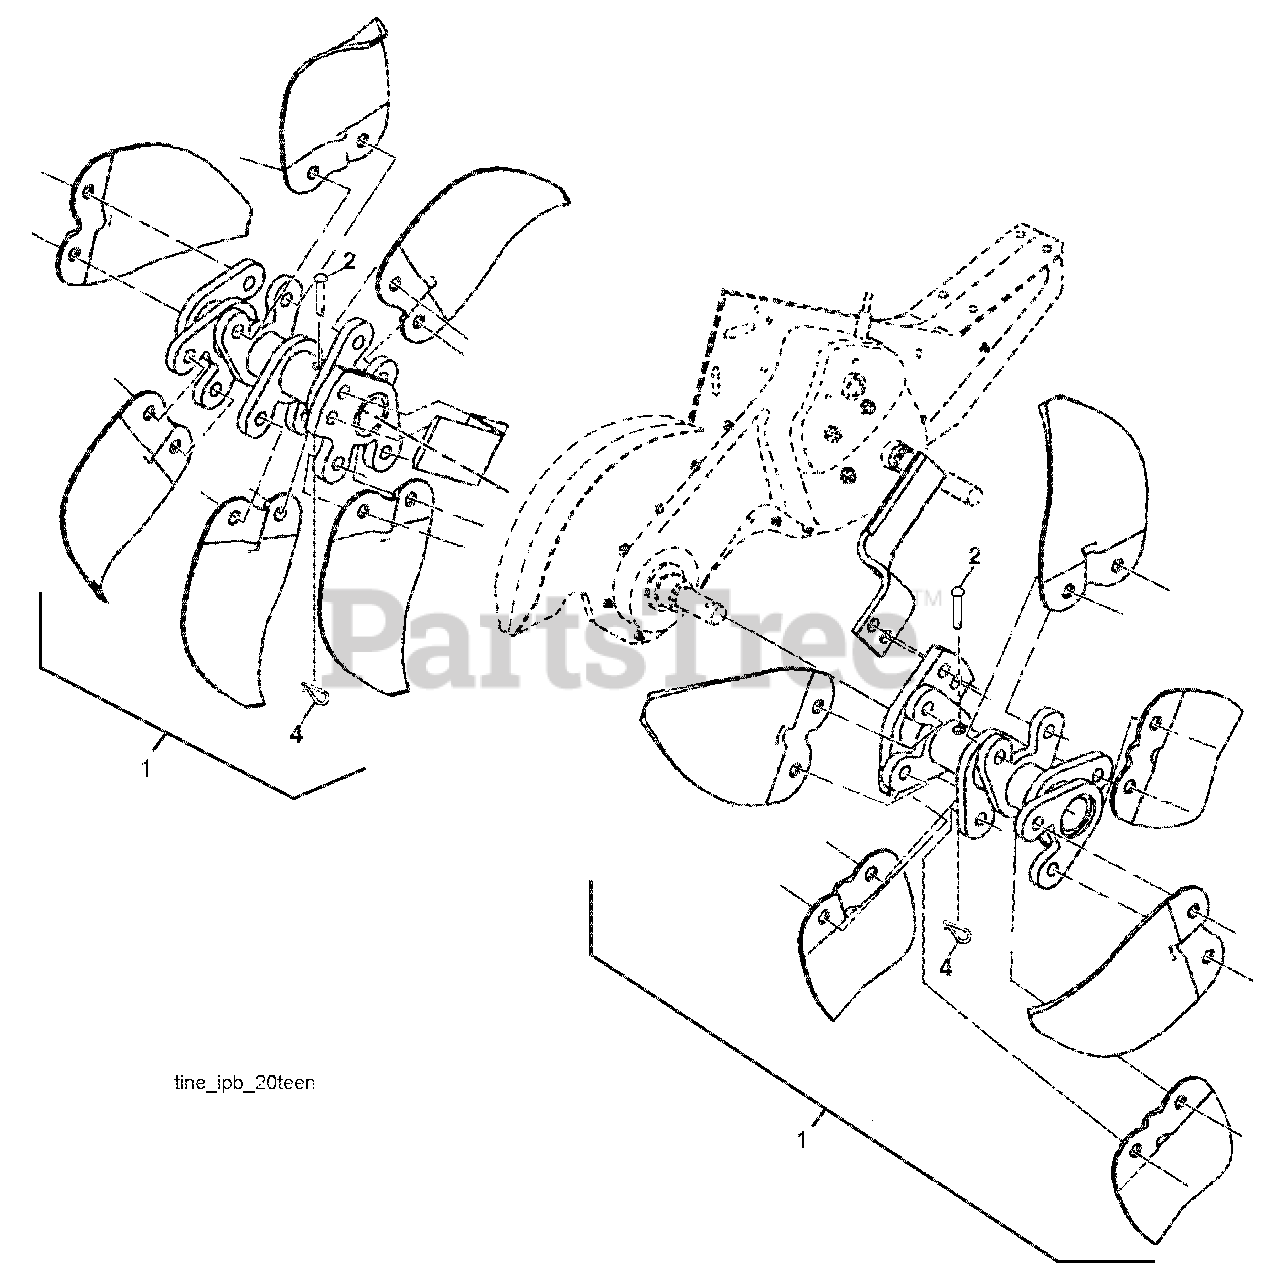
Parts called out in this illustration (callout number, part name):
1	TINE ASSEMBLY
2	Pin, Shear
4	Retainer, Spring
